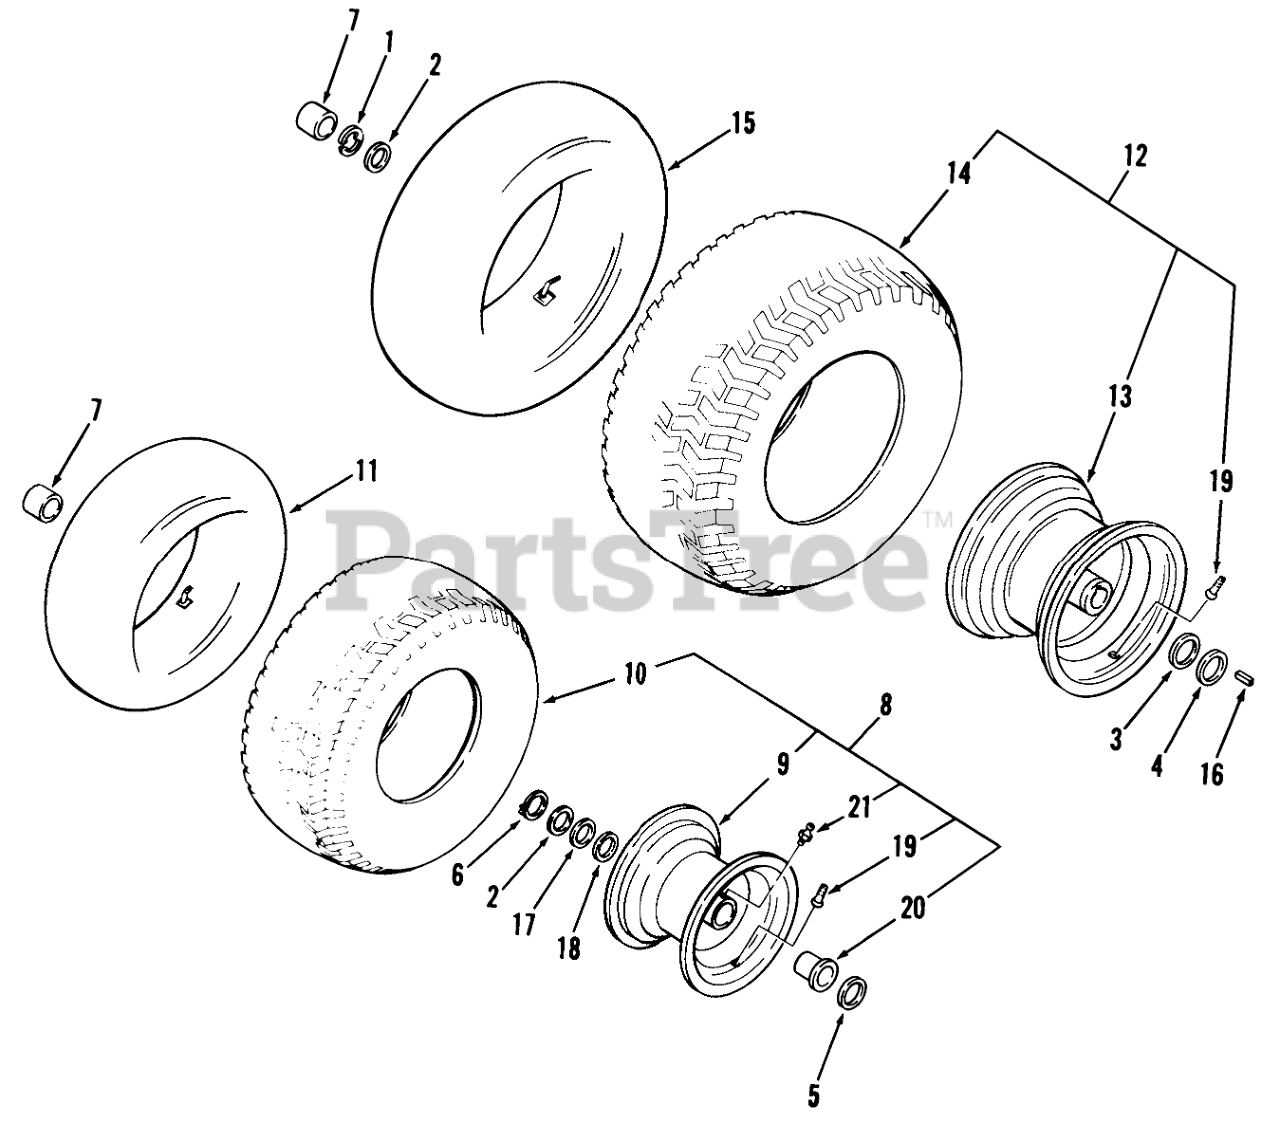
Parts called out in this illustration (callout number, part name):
1	E Ring
3	WASHER-SHIM
4	WASHER
5	Washer
6	Snap Ring
7	HUB CAP
8	Wheel & Tire Assembly
8	Assy-Wheel & Tire Front
9	ASSY-RIM
9	Rim
11	Tube (Service Only)
11	INNER TUBE
12	Assy-Wheel & Tire Rear
13	Rear Wheel
14	TIRE 18 X 9.50-8
14	TIRE
15	Tube-Inner
15	Rear Tube-Service Only
16	SQ KEY
17	WASHER
18	WASHER-SHIM
19	VALVE
20	FLANGE BEARING
21	Zerk
